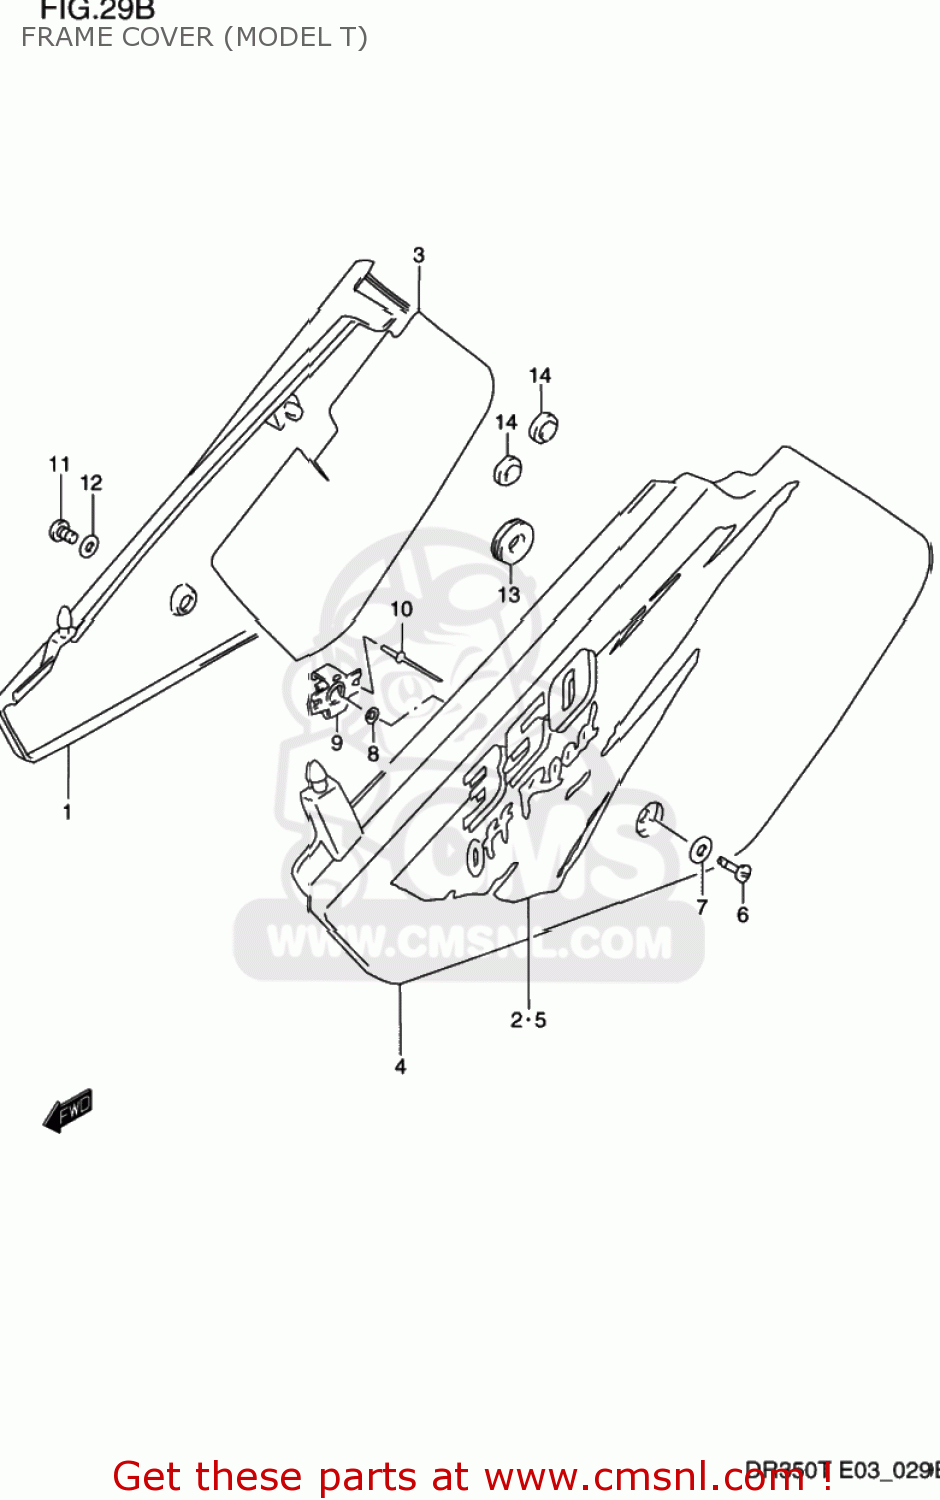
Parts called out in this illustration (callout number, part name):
1	COVER,FRAME,R(WHITE)
2	TAPE,FRAME COVER,R
3	SHIELD,FRAME COVER,R
4	COVER,FRAME,L(WHITE)
5	TAPE,FRAME COVER,LEFT
6	STUD,FRAME COVER,LEFT
7	WASHER
8	RETAINER,FRAME COVER STUD,L
9	PLATE,FITING
10	RIVET
11	SCREW
12	WASHER
13	CUSHION
14	CUSHION
